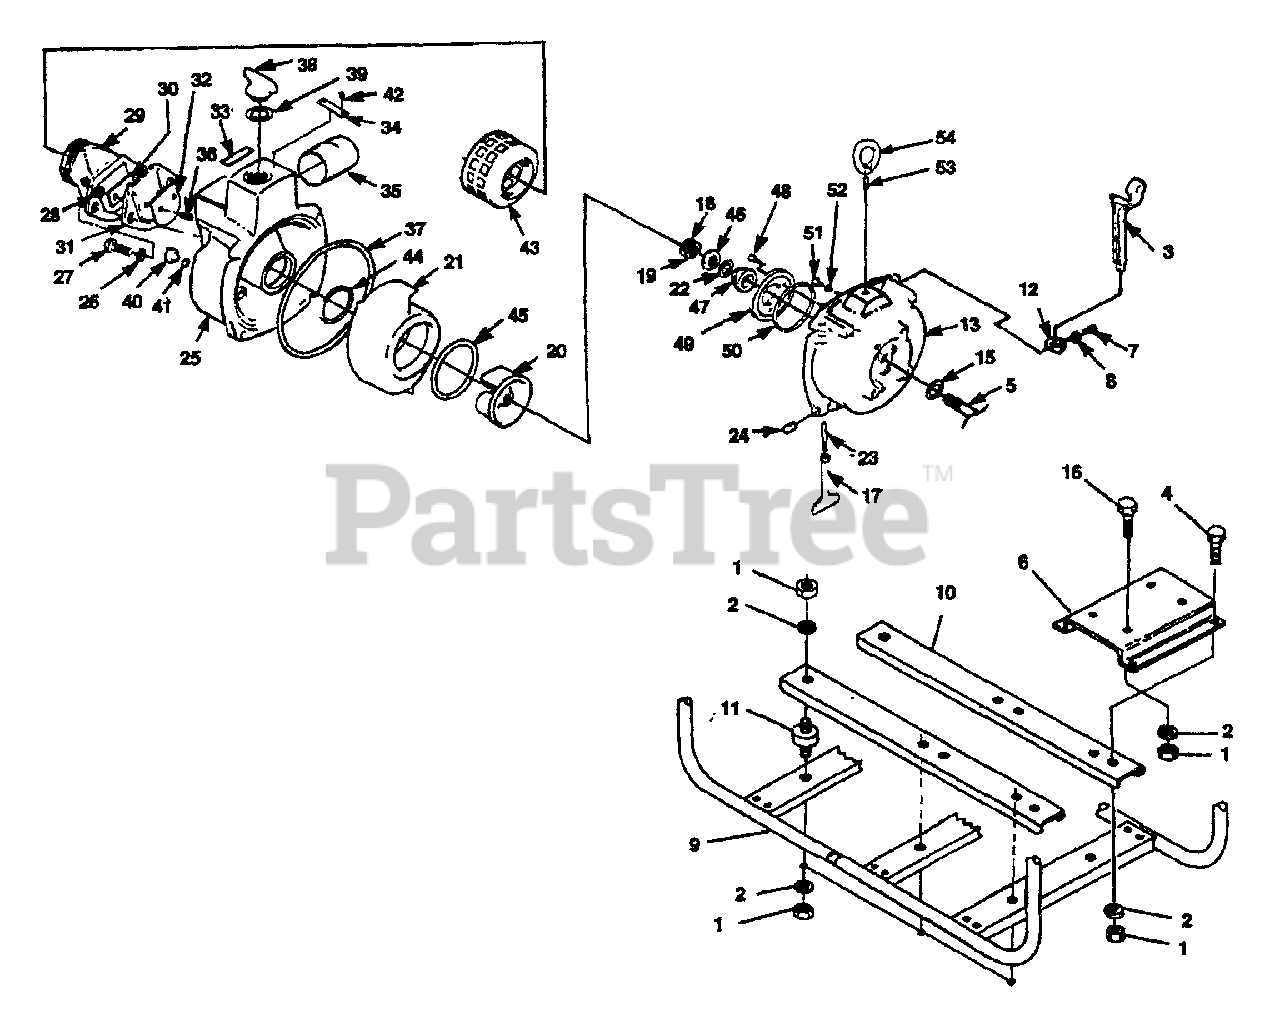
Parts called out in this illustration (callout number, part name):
1	NUT - Hex (5/16-18)
2	WASHER - Lock (5/16)
3	WRENCH - Spanner
4	SCREW - Hex hd. (5/16-18 x 1)
5	ENGINE
6	BRACKET-Pump engine
7	SCREW - Hex hd. (1/4-20 x 1/2)
8	WASHER - Flat (1/4")
9	ROLL CAGE
10	CHANNEL, ENGINE
11	ISOLATOR VIBRATION
12	BRACKET- Spanner Wrench
13	BODY - Pump
15	SLINGER
16	SCREW - Hex hd. (5/16-18 x 1 3/4")
17	HANDLE - Disconnect
18	SHIM - Impeller (.032")
19	SHIM (.015")
20	IMPELLER
21	HOUSING - Impeller
22	SHIM - Impeller (.010")
23	STUD - Handle
24	PIVOT- Handle
25	HOUSING - End
26	WASHER - Lock (1/2")
27	SCREW - Cap hex hd. (1/2-13 x 1 1/4")
28	NUT - Hex (10-32)
29	FITTING - Pump Section
30	VALVE - Plate
31	VALVE - Flapper
32	VALVE - Plate
34	PLATE - Warning
36	SCREW (10-32 x 1/2")
37	GASKET - Pump body
38	PLUG - Filler
39	GASKET- Wing nut
40	CAP - Drain & Filler
41	GASKET-Drain & Filler cap
42	TACK - Metal
43	STRAINER - Suction
44	GASKET- End plate
45	GASKET- impeller housing
46	NUT- Impeller
47	SEAL - Shaft
48	SCREW - Hex cap (1/4-20 x 5/8")
49	PLATE - Wear
50	"O" RING
51	SCREW - Cap hex hd. (3/8-16 x 1 1/4")
52	WASHER - Sealing
53	STUD, Eye nut
54	NUT, Eye
